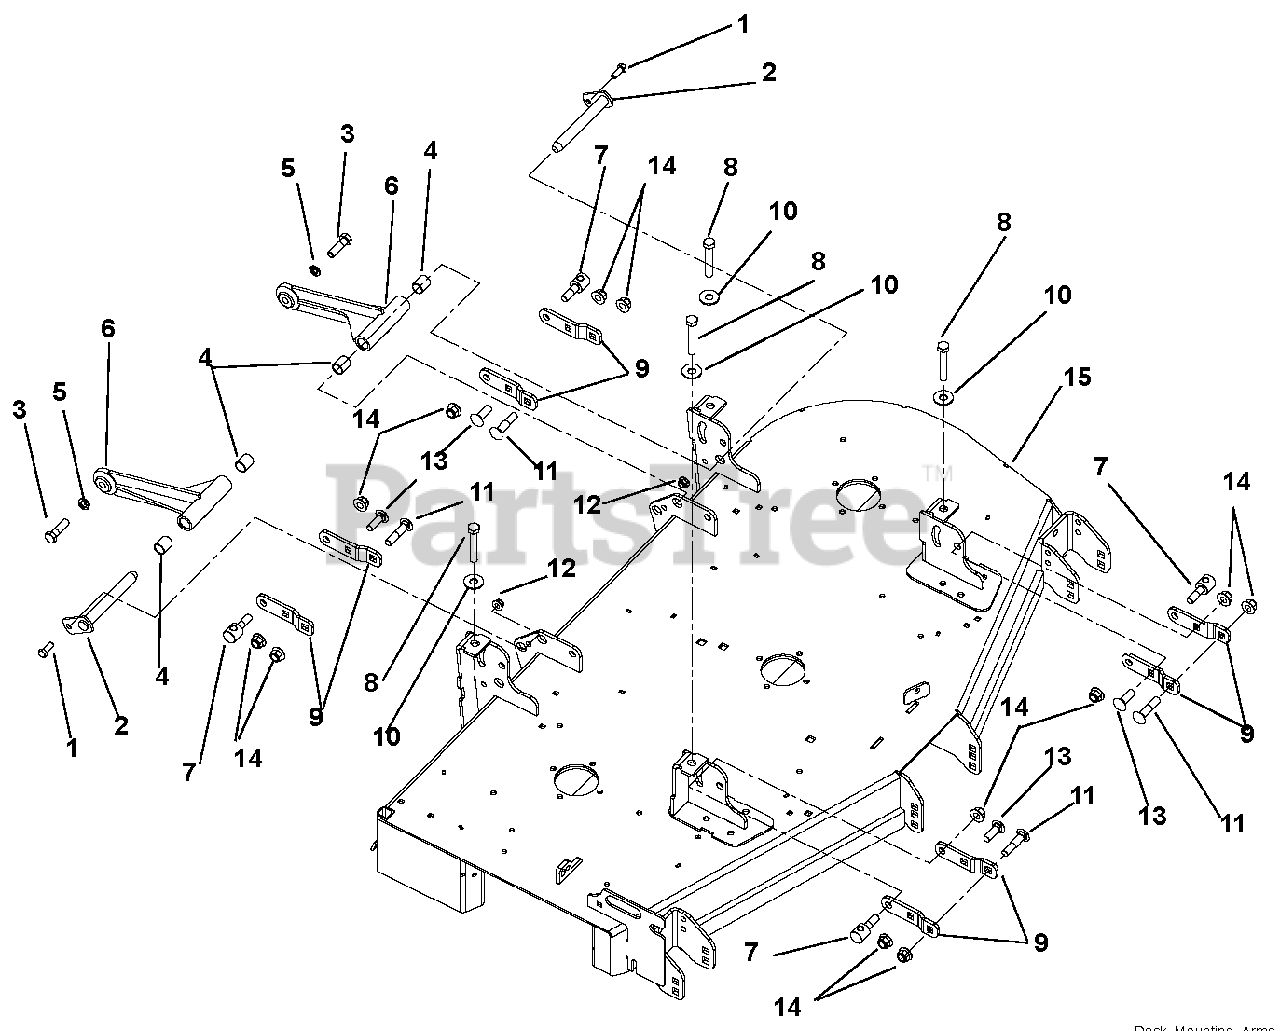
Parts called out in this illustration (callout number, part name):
1	Bolt, Hex .38-16 x 1.00
2	Weldment, Mower Mounting Pin
3	Bolt, Hex .50-13 x 1.75 Grade 5 EP80
4	Bearing, .75 x .875 x 1.00
5	Washer, Locking .50 x .125 Regular
6	Deck Pusher Arm Weldment, Black
7	Trunnion, .50-13
8	Bolt, Hex .50-13 x 3.00
9	Bracket, Deck Leveling
10	Washer, Flat Steel .563 x 1.38 x .109
11	Bolt, Round Head Square Neck .50-13 x 2.25
12	Nut, Locking Nylon Flange .38-16
13	Bolt, Round Head Square Neck .50-13 x 1.50
14	Nut, Locking Nylon Flange .50-13
15	48" Deck, Side Discharge (Models 991079, 991095)
